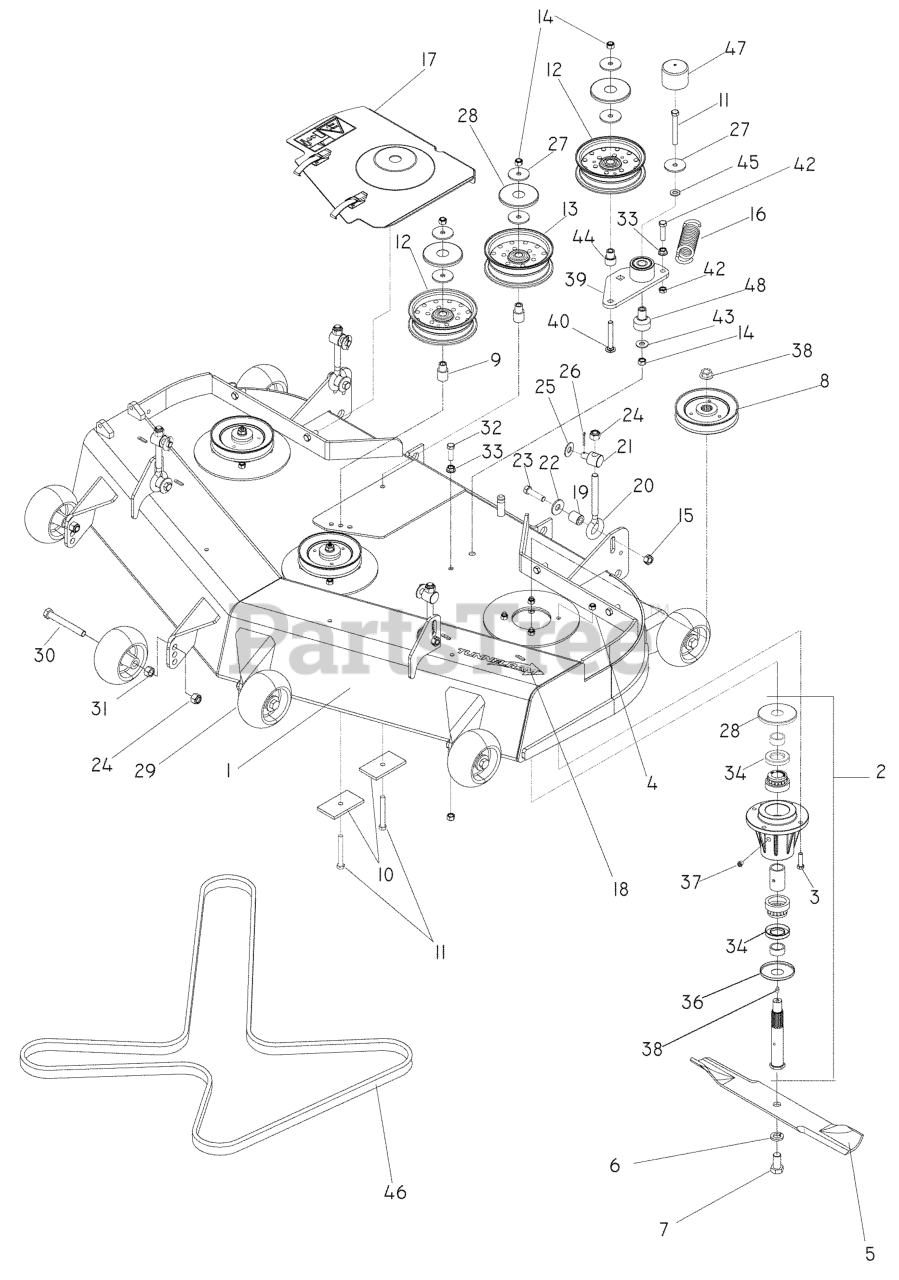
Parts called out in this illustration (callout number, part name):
1	DECK W/DECALS 52" HUS
2	HSG KIT 52/61 RIBBED
3	HCS 5/16C X 1 1/4
4	NUT 5/16 NYLOC
5	BLADE OEM 18"
6	LOCKWASHER 5/8
7	HCS 5/8F X 1 1/4
8	PULLEY, 52
9	IDLER BUSHING
10	SUPPORT PLATE
11	HCS 3/8C X 3
12	IDLER PULLEY
13	IDLER PULLEY (TALL)
14	NUT 3/8-16 NYLOC
15	NUT 7/16C CENTERLOCK
16	DECK SPRING
17	52" BELT SHIELD ASM - RH
18	DECAL, TUNNEL RAM 8"
22	SPRING WASHER - .50
23	HCS 7/16 - 14 X 1 3/4
24	NUT 1/2-13 HEX NYLOC ZD
25	WASHER 1/2 FLAT
26	PIN COTTER 1/8 X 1 ZD
27	WASHER, 3/8 SPEC
28	TOP DUST CAP
29	GAUGE WHEEL
30	HCS 1/2-13 X 4 GR 5 ZD
31	NUT HEX 1/2
32	HCS 3/8C X 1 1/4 GR5
33	NUT 3/8C WHIZ
34	SHAFT SEAL
35	BOTTOM DUST CAP
36	PLUG-VENTED
37	ZERK
38	NUT FLANGE 3/4-16
39	ARM-IDLER W/BRG
40	RHSNB 3/8-16 X 2.75
41	HCS 3/8-16 X 1-1/2
42	NUT 3/8-16 HEX JAM
43	WASHER 3/8 FLAT
44	BUSHING, IDLER
45	WASHER 3/8 SAE FLAT
46	PUMP BELT
47	CAP, VINYL
48	PIVOT, BEARING
